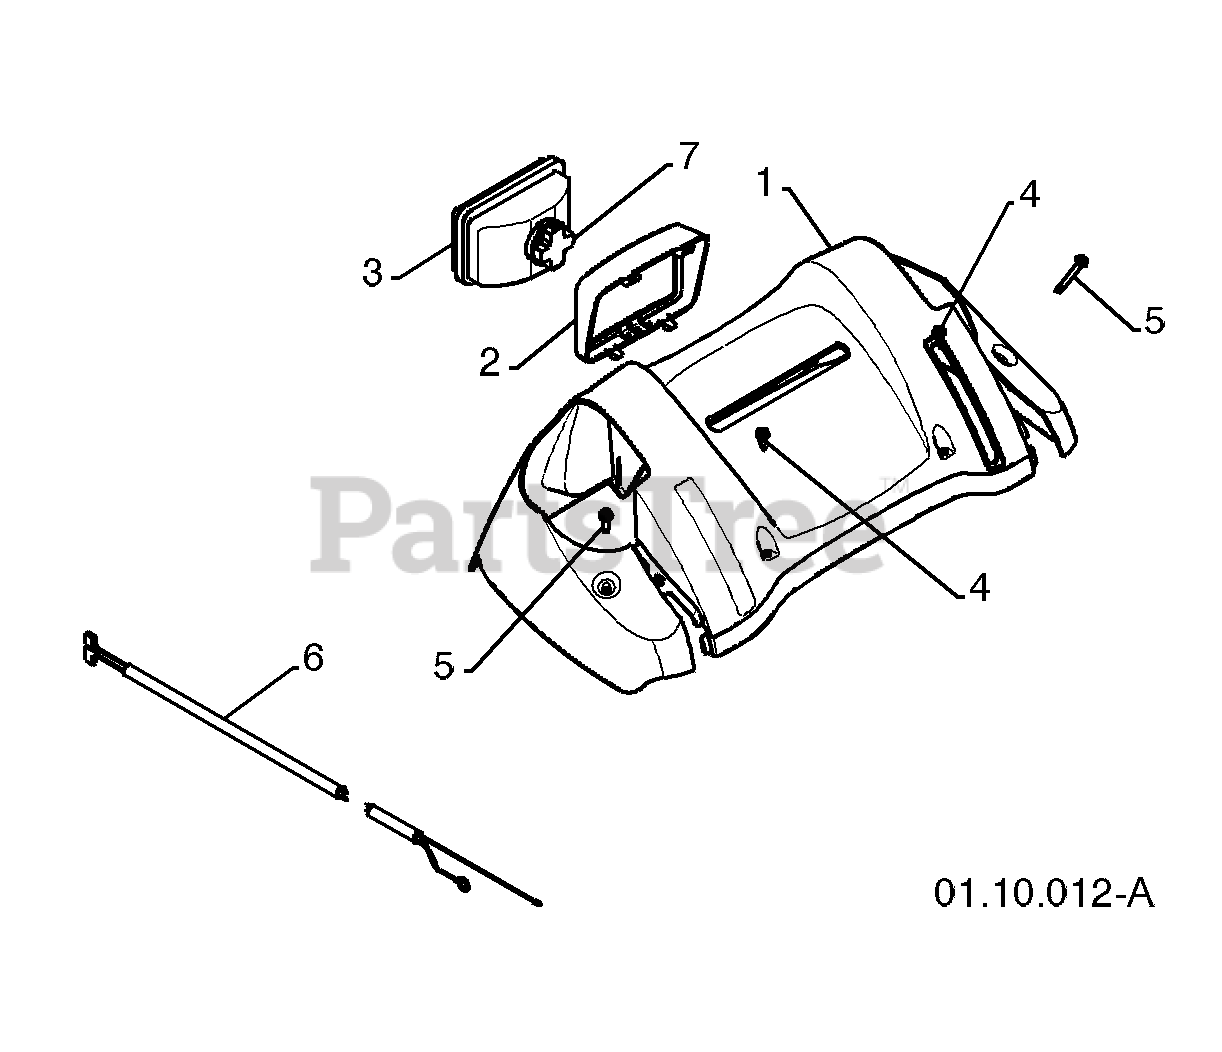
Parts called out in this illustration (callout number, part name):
1	CONSOLE PANEL GRAY
2	HEADLIGHT BEZEL GRAY
3	FLOOD HEADLIGHT
4	SHOULDER SCREW 10-24 X .625
5	SCREW 10-24 X 1.25
6	WIRE HARNESS
